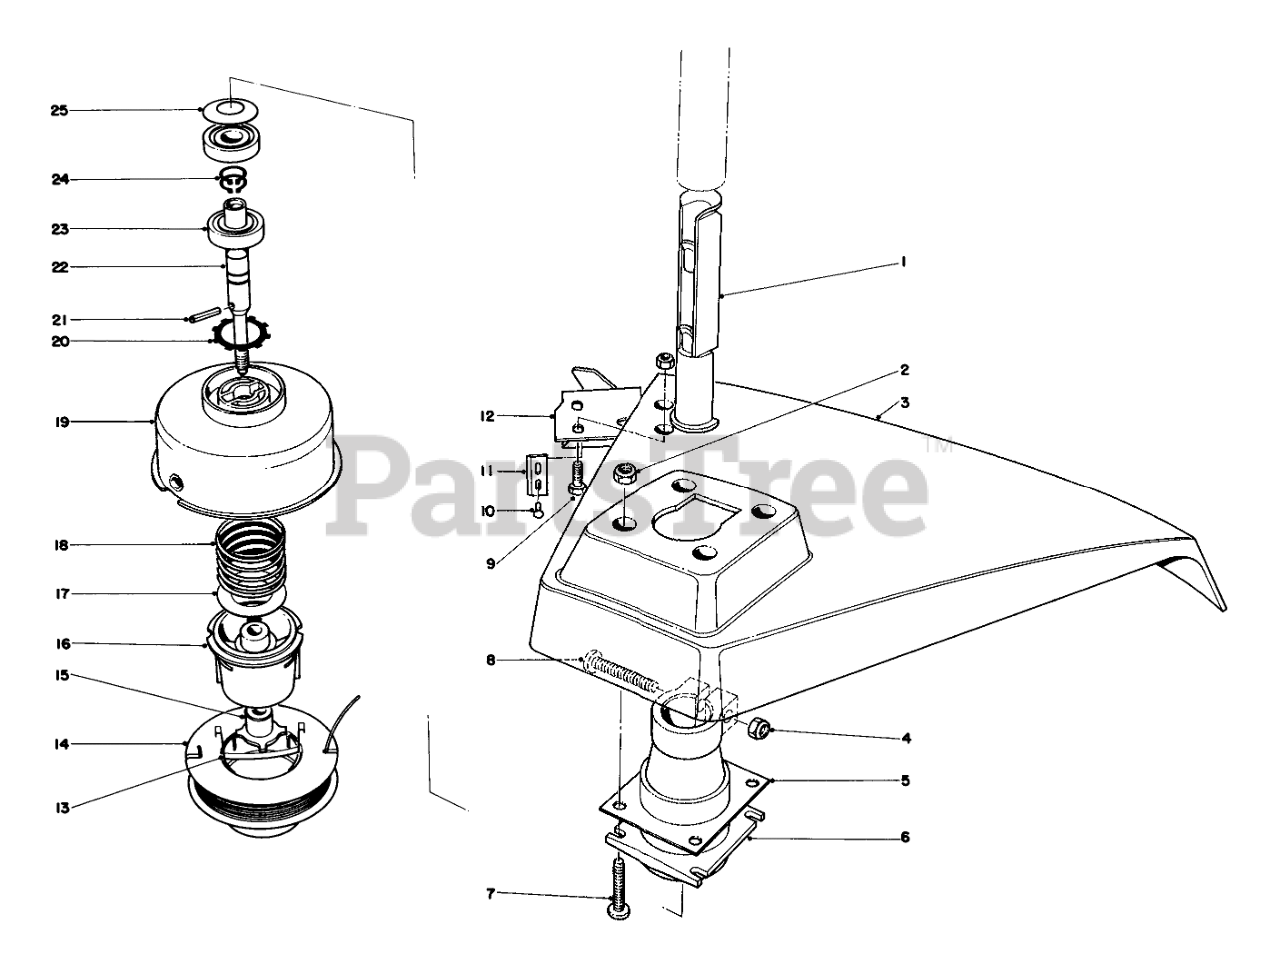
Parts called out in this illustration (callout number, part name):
1	Insert-Pole End
2	NUT-LOCK, NI
3	Shield
4	NUT-LOCK, NI
5	Gasket-Grass Shield
6	Bearing Housing Assembly (Incl. Ref. #20-25)
7	SCREW-PPH
8	Screw-Pan Head Machine
9	SCREW-HWH
10	Rivet
11	Blade-Knife
12	Bracket & Blade Assembly (Incl. Ref. #10-11)
13	SADDLE-SPOOL CAP
14	Spool & Line Assembly
15	DRIVER
16	SPOOL CORE
17	WASHER-FLAT
18	SPRING COMPRESSION
19	DRUM/EYELET
20	Spring Grip-Ext. Tooth
21	COIL PIN
22	Power Shaft
24	RING-Retaining
25	Washer
